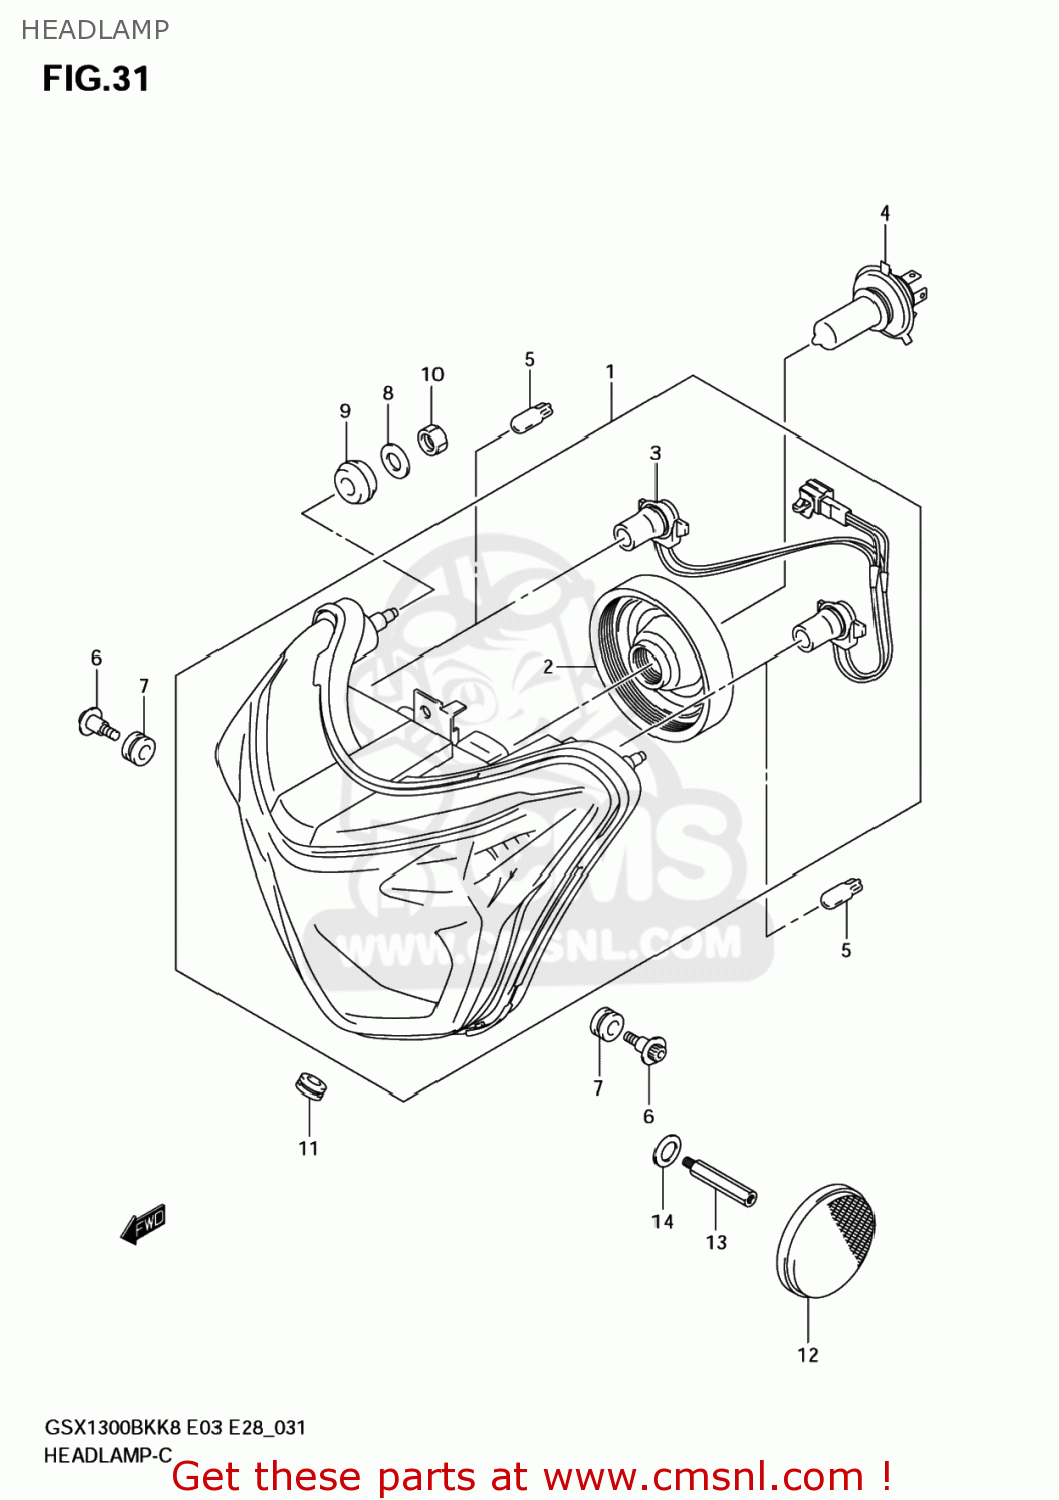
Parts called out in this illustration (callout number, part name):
1	HEADLAMP ASSY
2	COVER,SOCKET
3	CORD ASSY
4	BULB(12V60/55W,H4)
5	BULB(12V5W)
6	SCREW,SPEEDOMETER
7	CUSHION,METER
8	WASHER(6.5X20X1.6)
9	CUSHION
10	NUT
11	CUSHION
12	REFLECTOR,REFLEX
13	BOLT
14	WASHER(9X19X1.0)
